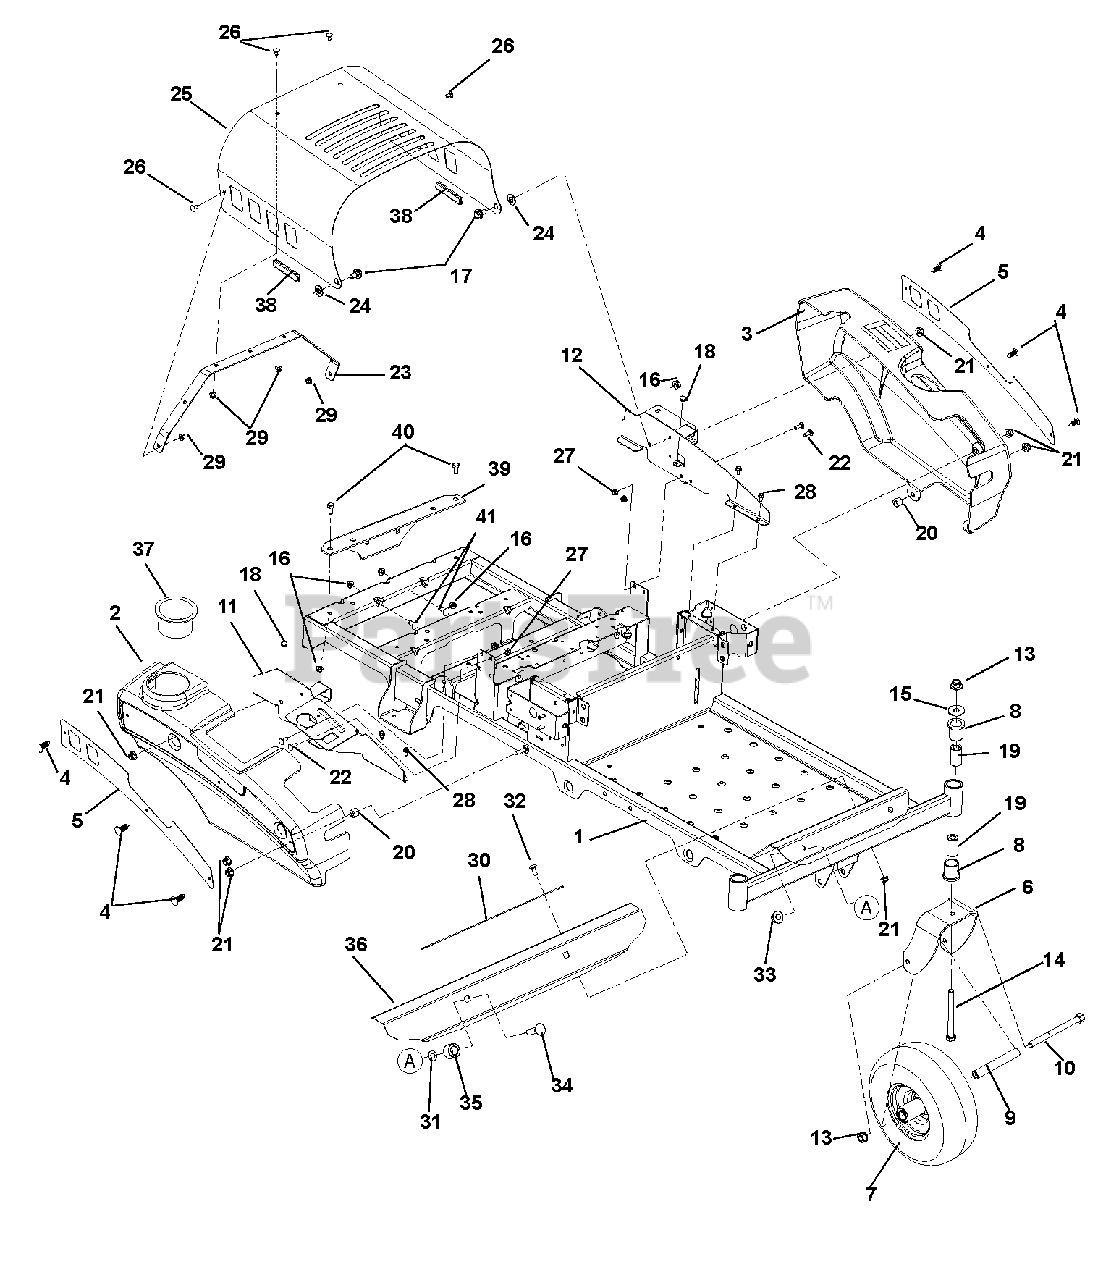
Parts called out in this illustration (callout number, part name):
1	Weldment, Frame
2	Fender, Right Hand
3	Fender, Left Hand
4	Rivet, Nylon
5	Plate, Fender
6	Fork, Caster
7	Wheel/Tire Assembly, 11.0 x 4.0 x 5.0
8	Bushing, Flange 1.00 x 1.25 x 1.50 x 1.50
9	Spacer, Wheel
10	Bolt, Hex .50-13 x 6.50
11	Weldment, Fender Mount Right Hand
12	Weldment, Fender Mount Left Hand
13	Nut, Locking, Top, Flange .50-13
14	Bolt, Hex .50-13 x 5.00
15	Washer, Flat Steel .511 x 1.441 x .125
16	Nut, Locking, Top, Flange .38-16 (915328)
17	Bolt, Shoulder .375-16 x .135
18	Bumper Grommet .125 x .250 Diameter
19	Spacer, Caster
20	Bushing, Sleeve .391 x .688 x .52
21	Nut, .31-18 Nyloc Flange
22	Bolt, Round Head Square Neck .25-20 x .75
23	Hood Brace
24	Washer, Flat, Nylon .52 x 1.00 x .08
25	Hood, Zoom
26	Bolt, Round Head Square Neck .25-20 x .50
27	Nut, .25-20 Nyloc Flange
28	Screw, Tapping .25-20 x .50 Hex Washer Head Thread
29	Nut, Locking Top Flange .25-20
30	Grip, Adhesive (1" x 16" BLK)
31	Nut, Push .50
32	Bolt, Round Head Square Neck .31-18 x .75
33	Nut, Locking Nylon Flange .50-13
34	Bolt, Round Head Square Neck .50-13 x 1.75
35	Tube, Upper Control Pivot
36	Foot Rest
37	Cupholder
38	Edging, Clutch Paddle-2.00"
39	Plate, BBZ Hitch Kit Plate (915328)
40	Bolt, Hex .38-16 x .75 (915328)
41	Bolt, Round Head Square Neck .31-16 x .75 (915328)
